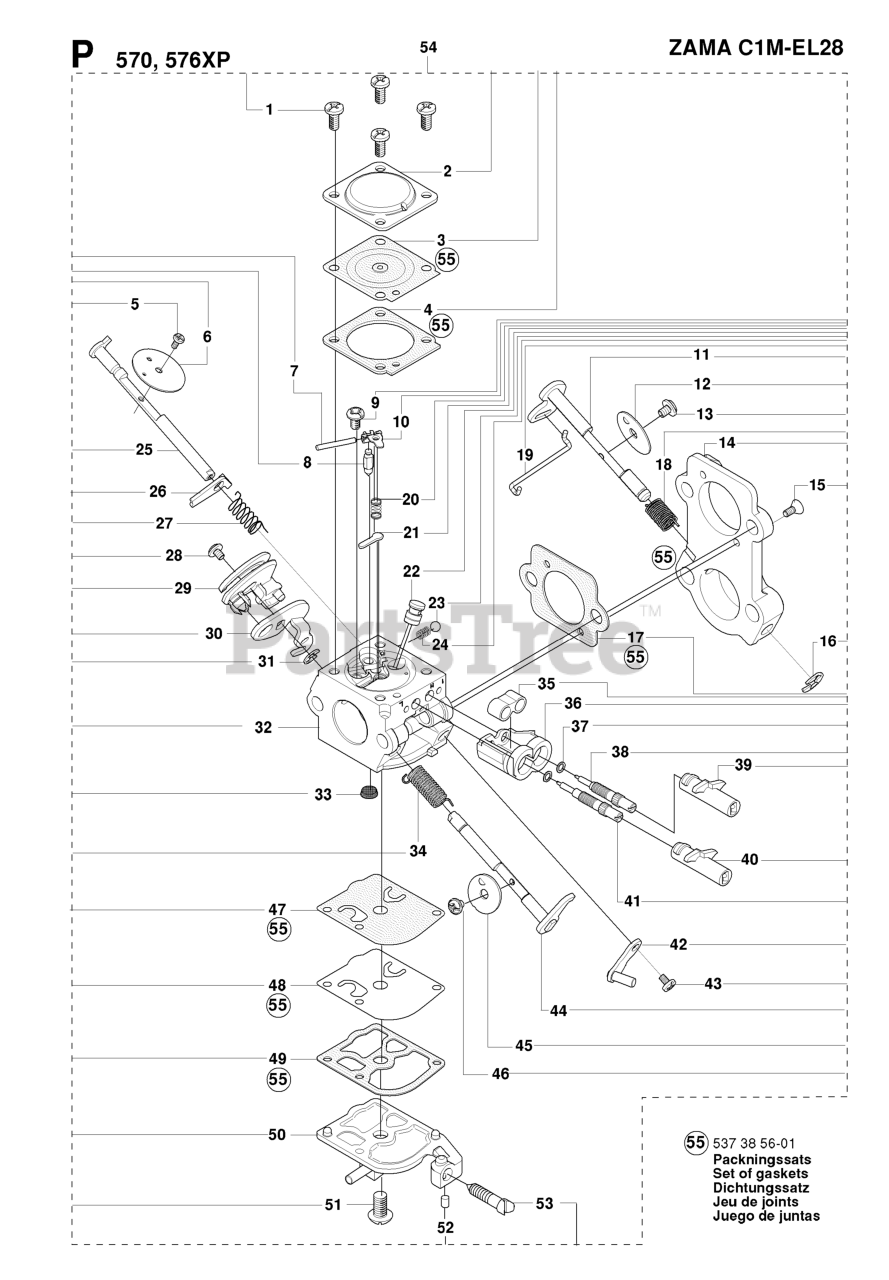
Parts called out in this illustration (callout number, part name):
6	CHOKE FLAP
7	PIN RETAINING SCREW
8	INLET NEEDLE
12	THROTTLE FLAP
14	RP CARBURETOR
25	CHOKE SHAFT
32	RP CARBURETOR
38	NEEDLE HIGH SPEED
41	LOW SPEED NEEDLE
44	THROTTLE SHAFT
47	PUMP DIAPHRAGM
54	RP CARBURETOR
55	GASKET SET
